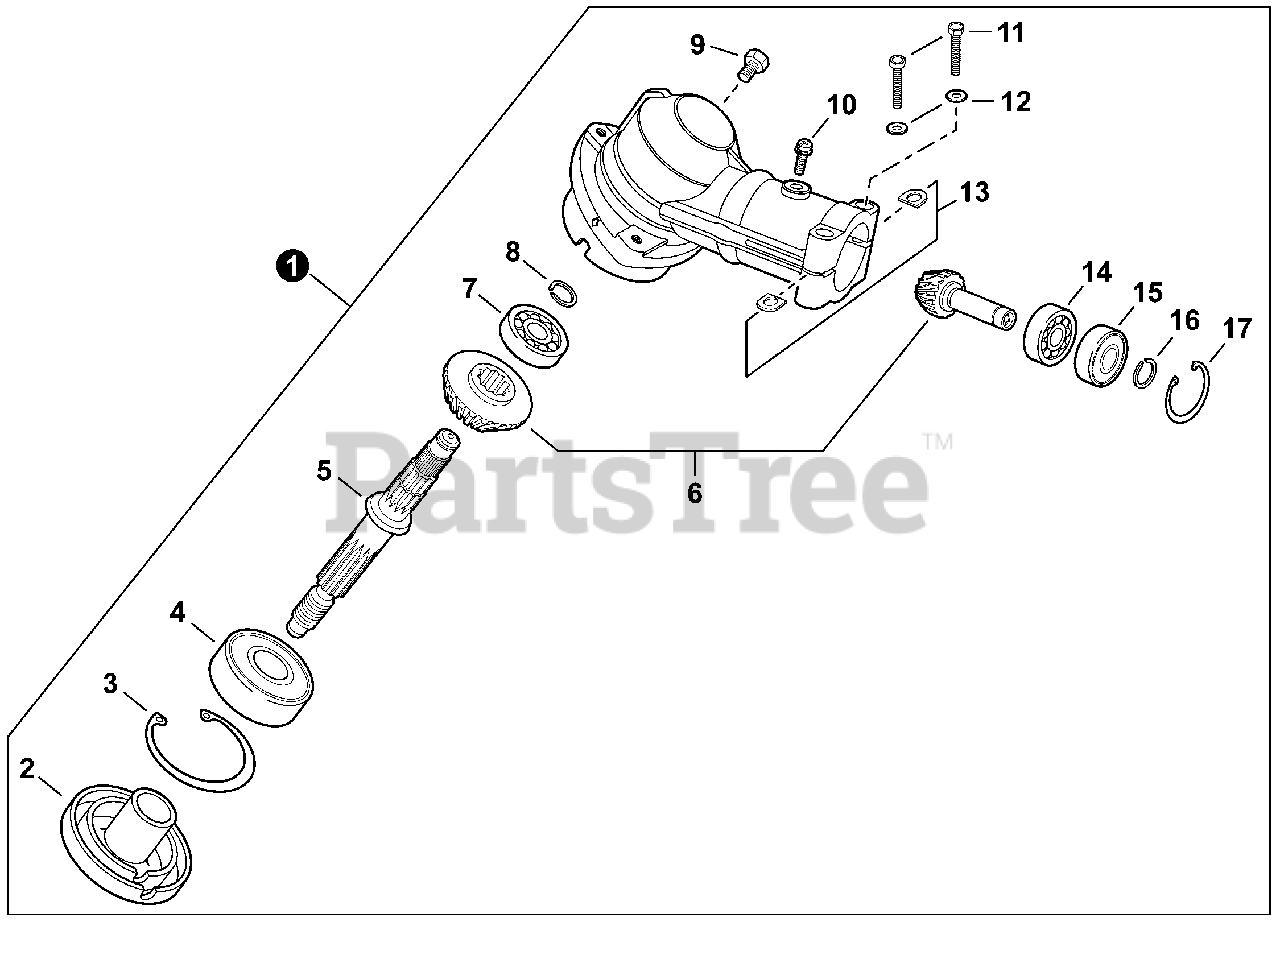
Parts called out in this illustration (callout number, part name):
1	GEAR CASE ASSY
2	PLATE, ADAPTOR - UPPER
3	RING, SNAP Ø42
4	BEARING, BALL 6302
5	SHAFT, GEAR
6	GEAR SET
7	BEARING, BALL 629
8	RING, SNAP Ø12
9	BOLT M8×8
10	SCREW 5×12
11	BOLT 5×35 SP
12	WASHER, FLAT 5.5×10×0.8
14	BEARING, BALL 6900
15	BEARING, BALL 6900Z
16	RING, SNAP Ø10
17	RING, SNAP Ø22
